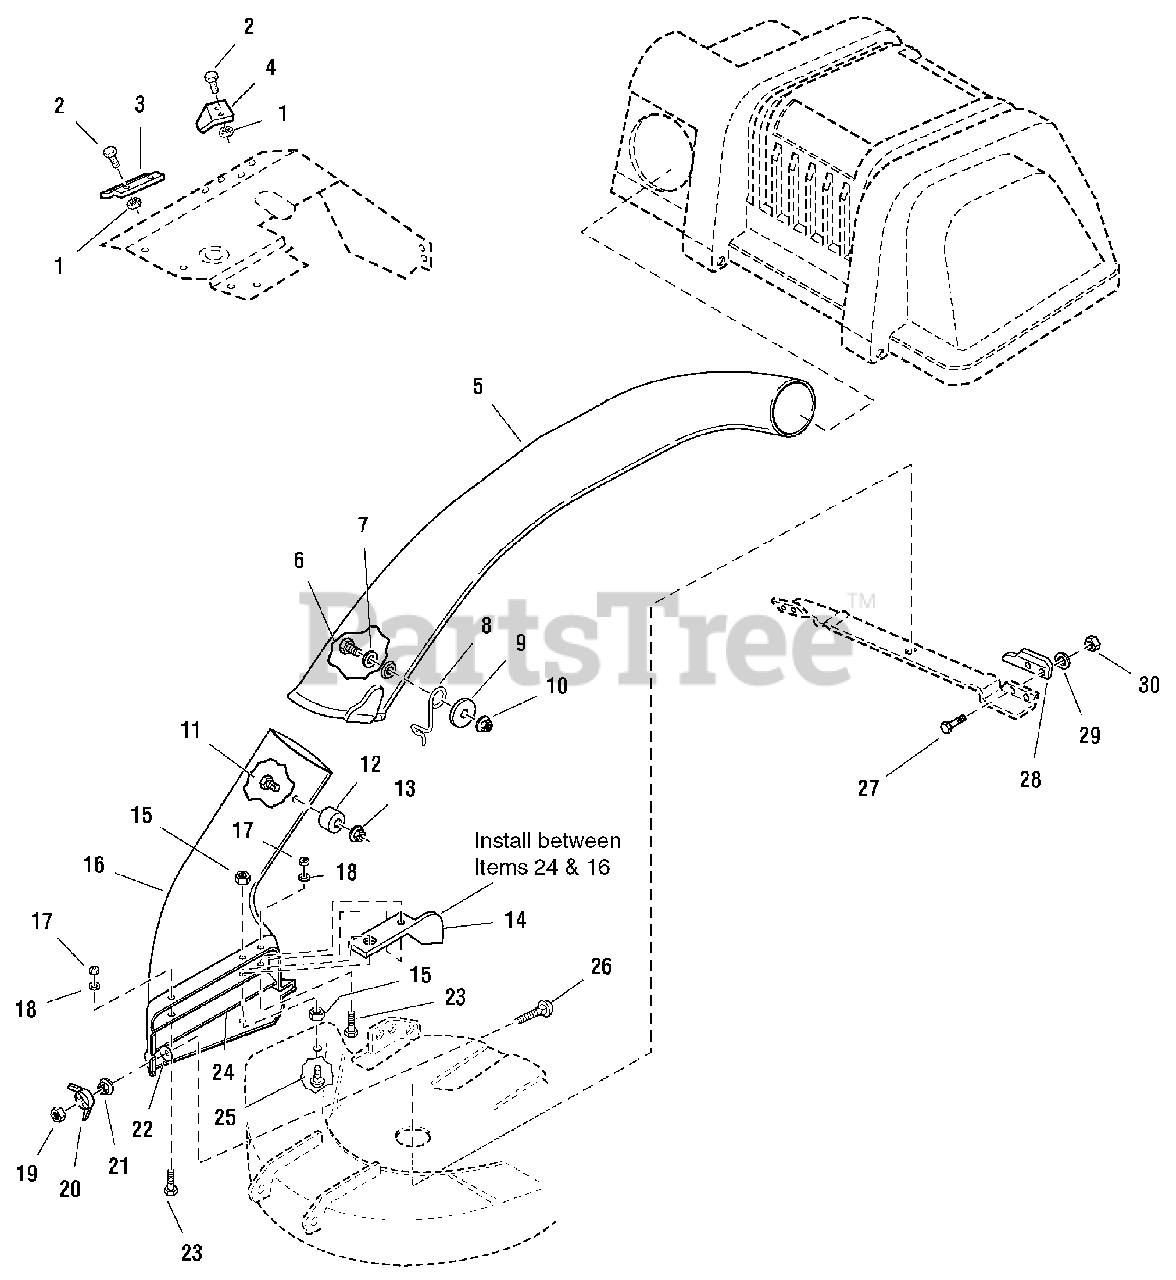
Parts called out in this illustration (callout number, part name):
1	NUT, Hex Washer Assembly, Hex, #10-32
2	SCREW, Truss Head, #10-24
3	EXHAUST SHIELD, Front
4	EXHAUST SHIELD, Rear
5	TRANSFER TUBE
6	CAPSCREW, Hex Head, 5/16-18 x 3/4
7	WASHER, 5/16
8	LATCH, Tube
9	WASHER, Flat, 3/16
10	NUT, Flange Lock, 5/16-18
11	SCREW, Head Head, 5/16-18 x 3/4
12	WASHER, Special, 11/32 x 7/8 x 1-3/4
13	LOCKNUT, Hex, 5/16-18
14	BAFFLE, Corner
15	NUT, Hex Jam, 5/16-18
17	NUT, Hex Head, #10-24
18	WASHER, Flat, 3/16
19	NUT, Hex Centerlock, 5/16-18
20	WING NUT ASSEMBLY, 5/16
21	NUT, Hex Flange, 5/16-18
23	SCREW, Flat Head, #10-24 x 5/8
24	STRAP, Reinforcement
25	BOLT, Carriage, 5/16-18 x 1 1/4
26	CARRIAGE BOLT, 5/16-18 x 2-1/4
27	CAPSCREW, 1/4-20 x 5/8, Gr. 8
28	LIFT PLATE
29	LOCKWASHER, Spring, 1/4
30	LOCKNUT, Hex, 5/16-18
